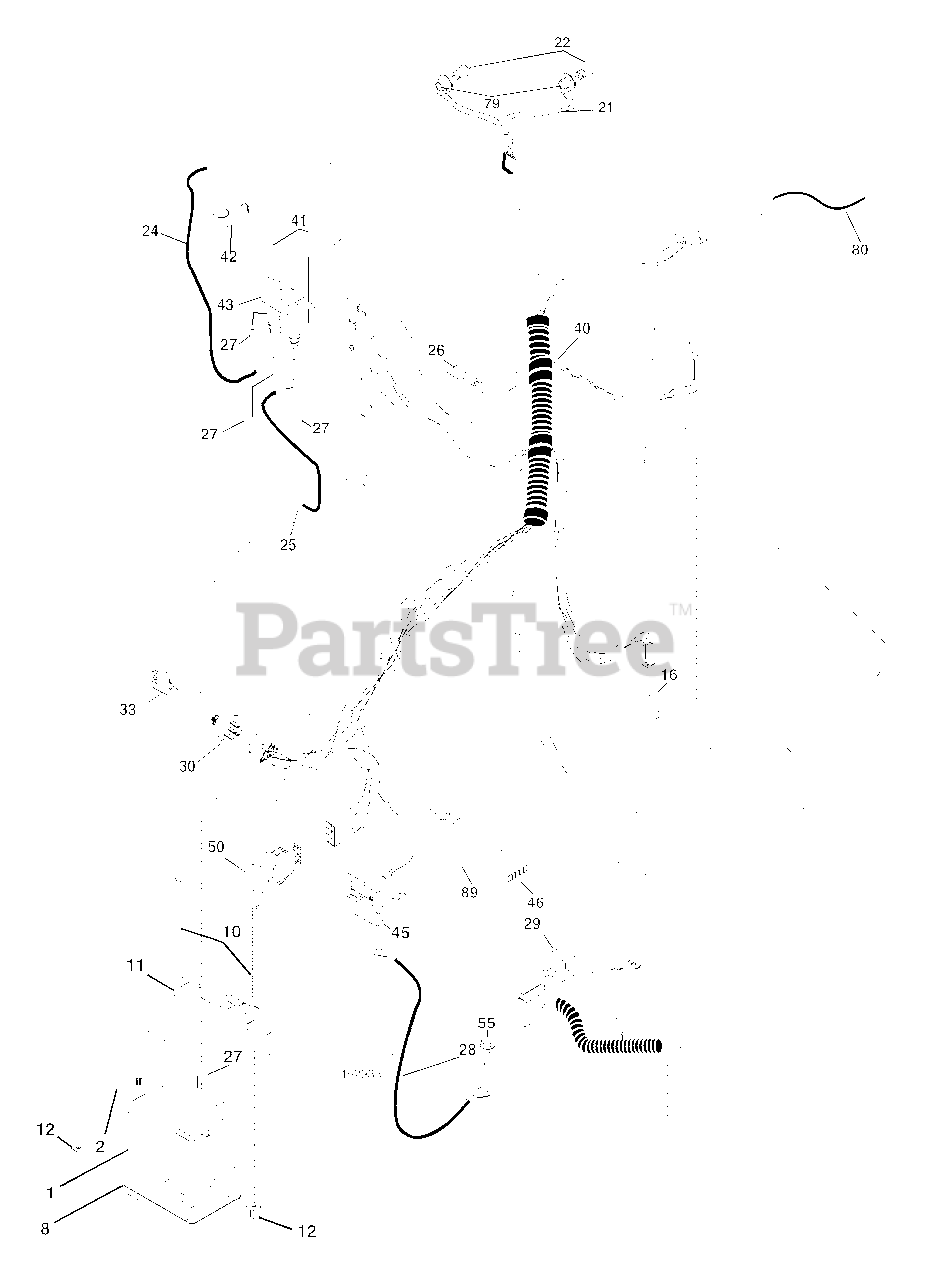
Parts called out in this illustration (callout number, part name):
1	Battery
2	Bolt, Hex 1/4-20 x 3/4
8	Tray, Battery
10	Bolt, Battery, Front 1/4-20 x 7-1/2
11	Holddown, Battery, Front
12	Nut, Push, Nylon, Battery, Front 1/4
16	Switch, Interlock
21	Harness, Light
22	Bulb Light #1156
24	Cable Starter
25	Cable
26	Fuse
27	Nut, Hex, Keps 1/4-20 unc
28	Cable, Ground
29	Switch, Seat
30	Switch, Ignition
33	Key
40	Harness, Ignition
41	Screw Thd Cut 1/4-20 x 1/2
42	Cover Terminal
43	Solinoid w/brass plunger
45	Ammeter
46	Hourmeter
50	Switch, PTO
55	Screw, Thd. Roll. 5/16-18 x 1/2
79	Socket Asm Bulb Twistlock
80	Harness Clutch EXV
89	Bracket Snap-In Hourmeter
